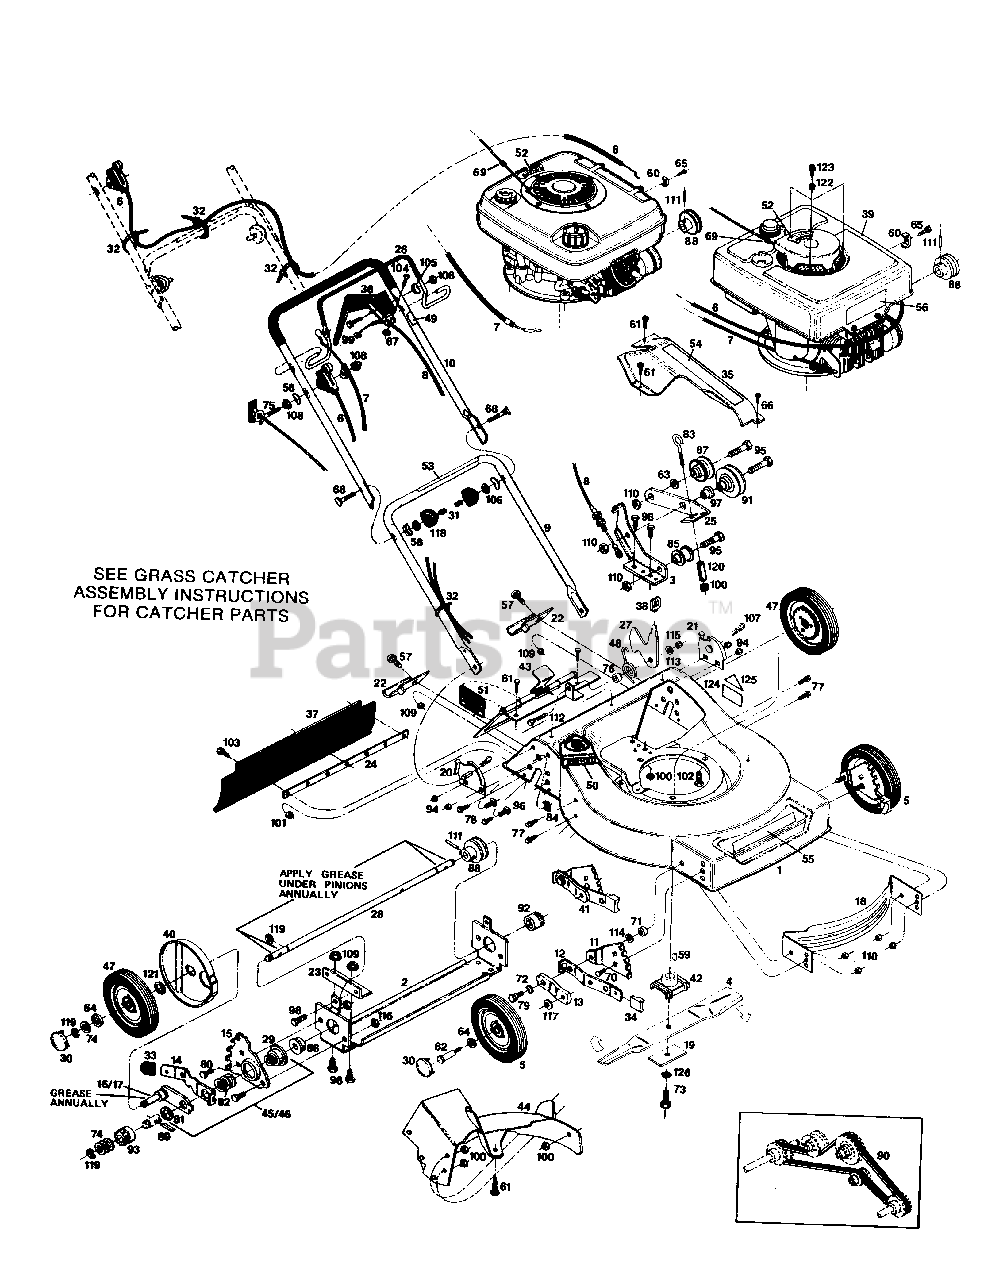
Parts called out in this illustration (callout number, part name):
2	Bracket-Drive Support
3	Bracket-Idler Mounting
5	Wheel-Front, 8 x 1.75
6	Control-Throttle w/Cable
7	Cable-Engine/Blade Control
8	Cable-Wheel Drive Control
9	Handle-Lower
10	Handle-Upper
11	Plate-Back, Front Adjuster
12	Lever-Setting, Front Adjuster
13	Lever, Wheel, Front
14	Lever, Setting, Rear Adjuster
15	Plate-Back, Rear Adjuster
16	Lever-Wheel w/Pin Rear RH
17	Lever-Wheel w/Pin Rear LH
18	Baffle-Front
19	Washer-Blade
20	Bracket-Handle RH
21	Bracket-Handle LH
22	Hook-Grass Catcher
23	Bracket-Drive Support
24	Strip-Backing
25	Arm-Idler
26	Bail-Engine/Blade Control
27	Latch-Grass Catcher
28	Shaft-Drive
29	Sleeve-Stepped. Rear Adjuster
30	Cap-Wheel Hub
31	Cap-Bolt End, Plastic
33	Tip-Adjuster Lever. Rear
34	Tip-Adjuster Lever. Front
35	Cover-Belt
36	Control-Wheel Drive
37	Shield-Trailing
38	Knob-Catcher Latch
39	Shroud-Engine
40	Cover-Dust, Rear Wheel
41	Adjuster-Height, Complete. Front
42	Adapter-Blade
43	Door-Catcher Opening
44	Baffle Assembly, Rear
45	Adjuster-Height, Complete, LH Rear
46	Adjuster-Height, Complete. RH Rear
47	Wheel-Rear w/Gear
48	Spring-Torsion, Catcher Latch
49	Decal-Drive Control Instructions
50	Decal-Danger, Discharge Chute
51	Decal-Caution, Catcher Door
52	Decal-Warning, Blade
53	Decal-Starting Instructions
54	Decal-21" Rear Drive
55	Decal-Simplicity
56	Decal-5.0 HP
57	Bolt-Carriage 1/4-20 x 5/8
58	Washer-Curved 5,16
59	Key-Woodruff #6
60	Clamp-Throttle Cable
61	Screw-Hex Slotted #10 x 5/8
62	Bolt-Wheel, Front
63	Washer-Flat, 3/8 ID, 7/8 OD
64	Washer-Wheel Retaining
65	Bolt-Hex #10-32 x 1/4
66	Screw-Self Tap #6-20 x 1/2
67	Nut-Hex #8-32 Nylok
68	Bolt-Curved Head 5/16-18 x 2 1/4
69	Stop-Rope
70	Bolt-Carriage 3/8-16 x 3/4
71	Washer-Plastic, Front Adjuster
72	Washer-Spring, Front Adjuster
73	Bolt-Blade 3/8-24 x 1 1/4
73	Bolt-Blade w/Washer 3/8-24 x 1
74	Washer-Thrust 1/2 ID
75	Eyebolt-Rope Guide
76	Spacer-Catcher Latch
77	Bolt-Hex 1/4-20 x 1/2
78	Bolt-Self Tap 1/4-20 x 3/4
79	Bolt-Shoulder, Front Adjuster
80	Bolt-Hex, 3/8-16 x 1/2
81	Ring-Retainer 7/8
82	Washer-Spring, Rear Adjuster
83	Eyebolt-Idler Cable
84	Nut 1/4-20 Snap in
85	Pulley-Idler
86	Bearing-Drive Shaft
87	Pulley-Idler
88	Pulley-Drive
89	Pawl-Drive
90	Belt-Drive V
91	Pulley-Idler
92	Pinion-Wheel Drive LH
93	Pinion-Wheel Drive RH
94	Nut-Hex 5/16-18 Nylok
95	Bolt-Hex 3/8-16 x 1-3/4
96	Bolt-Carriage 5/16-18 x 3/4
97	Spacer-Idler
98	Bolt-Hex 1/4-20 x 5/8
99	Bolt-Hex 1/4-20 x 1 1/2
100	Nut-1/4-20
101	Nut-Hex #10-24 Nylok
102	Bolt-Hex 3/8-16 x 7/8
103	Bolt-Hex #10-24 x 1/2
104	Screw-Pan Head #8-32 x 5/8
105	Washer-Curved
106	Washer-Shakeproof 5/16
107	Cotter-Hairpin
108	Nut-Hex 1/4-20 Keps
109	Nut-Hex 1/4-20 Whiz
110	Nut-Hex 3/8-16 Lock
111	Pin-Roll 3/16 x 1
112	Bolt-Hex 1/4-20 x 1
113	Washer-Flat 1/4
114	Washer-Flat 3/8
115	Nut-Hex 1/4-20 Lock
116	Nut-Hex Jam 3/8-16
117	Washer-Belleville
118	Knob-Handle Retaining
119	Ring-Retainer
120	Sleeve-Idler Cable
121	Ring-Retainer, Dust Shield
122	Retainer-Engine Shroud
123	Bolt-Hex 1/4-20 x 1/2 TD FM
124	DECAL, Model Number
125	DECAL, OPEI
126	Lockwasher-3/8 Split HD
